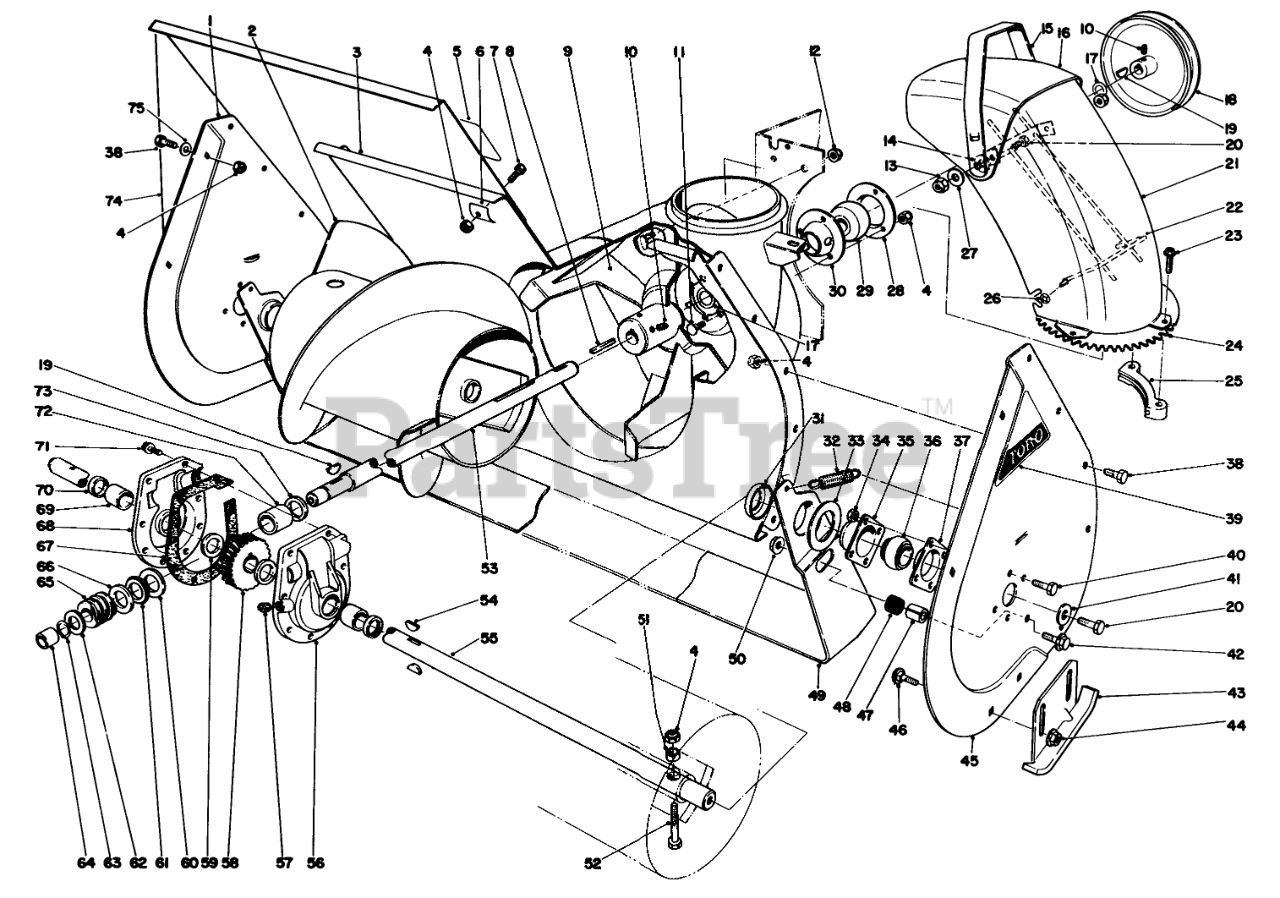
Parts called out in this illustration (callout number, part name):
1	RH AUGER SIDE PLT R
2	Auger Right
3	AUGER HSG WA RO
4	NUT-LOCK, NI
5	DECAL-WARNING, AUGER
6	SHIELD CLAMP R
7	SCREW-HH
9	IMPELLER WA RO
10	SCREW-SET, SQH
11	BOLT-CARR
12	NUT-LOCK, NI
13	NUT-LOCK, CONE
14	WASHER-RUBBER
15	DEFLECTOR HANDLE B
16	DEFLECTOR/DECAL
17	WASHER
18	IMPELLER PULLEY
19	KEY-WOODRUFF
20	SCREW-HH
21	CHUTE B
22	CHUTE GUARD WA 24
23	SPECIAL SCREW
24	Gear-Chute Swivel
25	CHUTE RETAINER
26	NUT-PUSH
27	WASHER-BELLEVILLE
28	FLANGE-CUP, BEARING
29	Ball Bearing
30	FLANGE-CUP, BEARING
31	Positioner-Scraper
32	SPRING-TENSION
33	SCRAPER BLADE SPACER
34	NUT-LOCK, CONE
35	BEARING-FLANGE, FRONT
36	BEARING
37	BEARING-FLANGE, REAR
38	SCREW-HH
39	AUGER SIDE PLT DECAL
40	SCREW-HH
41	WASHER
42	SCREW-HHF
43	AUGER SKID WA R
44	NUT-HHF, WHIZ
45	LH AUGER SIDE PLT R
46	SCREW-CARR
47	SCRAPER STOP SPACER
48	SCRAPER STOP CUSHION
49	24 SCRAPER BLD
50	NUT-HF
51	SPACER-HUB, AUGER
52	Auger Bolt
53	Shaft Impeller
54	KEY-WOODRUFF
55	24 AUGER SHAFT
56	Gear Case (Incl. Ref. #69 & 70)
57	PLUG-PIPE, SQH
58	GEAR-WORM, 27T
59	WASHER-THRUST
60	WASHER-THRUST
61	BEARING-THRUST
62	WASHER-THRUST
63	Ring-Snap
64	BUSHING
66	THRUST-WASHER
67	GASKET-CASE, GEAR
68	Gear Case (Incl. Ref. #69 & 70)
69	BUSHING
70	SEAL-OIL
71	SCREW-TAPTITE
72	BUSHING-SPECIAL
73	RING-QUAD
74	AUGER EXT 24 SCND R
75	WASHER-PLAIN
